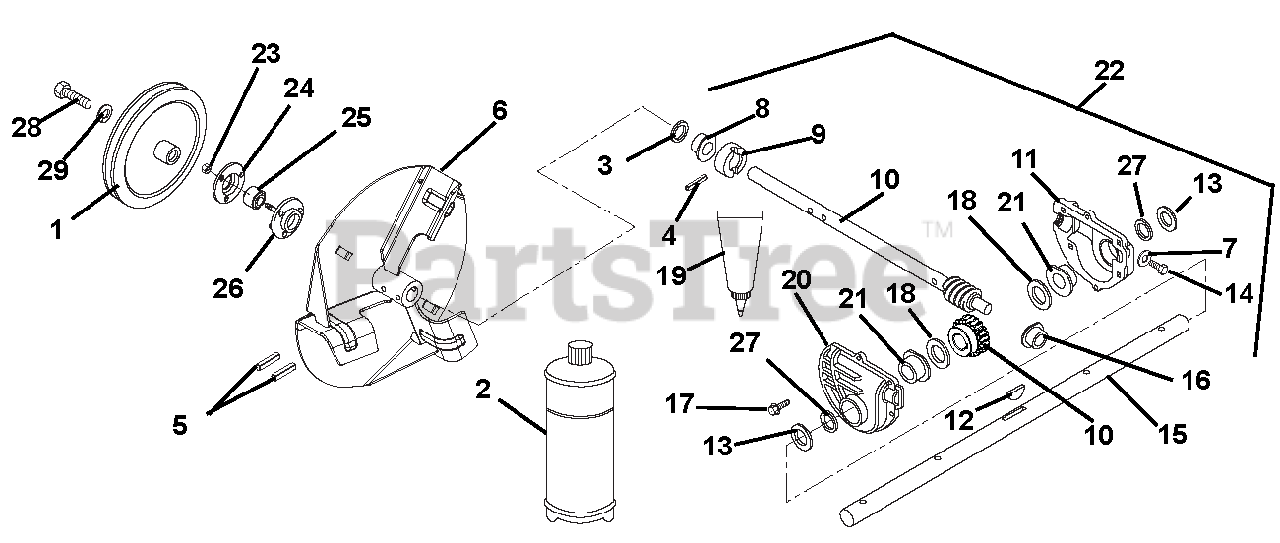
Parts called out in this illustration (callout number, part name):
1	PULLEY WITH HUB
2	ARIENS L3 LUBE, 8 OZ BOTTLE
3	SEAL-OIL.748X1.378X.276 RBR OD
4	@PIN-GRV .188X1.25 TP E ALLOY
5	PIN-ROLL .250X1.75
6	WELDMENT, IMPELLER,12" 3 BLADE
7	WSHR-FIBER .437X.656X.032
8	BSHG-FLG .750X1.000X.750X1.250
9	THRUST COLLAR, .75" ID
10	SHAFT AND WORM GEAR ASSEMBLY
11	GEARCASE CASTING, MACHINED LH
12	KEY-WDRF .19X.63 HRD #61
13	@WSHR-FL-STL.812X1.50X.135YWZC
14	SCR-TAP .38-16X.75 ROLOK YZ WX
15	SHAFT, RAKE - 20" (.750 DIA)
16	BSHG-FLG .502X1X.750
17	@SCR-TAP .25-20X1.00 HWH TR YZ
18	WSHR-FL-STL.755X1.375X.062YWZC
19	LOCTITE 518 GASKET--6ML TUBE
20	GEARCASE CASTING, MACHINED RH
21	BSHG-FLG .753X1.127X.500X1.501
22	GEARCASE, 20" ALUM, SMALL CD
23	@NUT-LK-CTR .25-20 YWZC
24	BEARING FLANGE
25	BRG-BALL .750X1.750X.50
26	BEARING FLANGE
27	SEAL-OIL .750X1.375X.250
28	BLT-HEX .31-24X.75 YWZC GR5
29	WSHR-LK .312X.097 HVY YWZC
